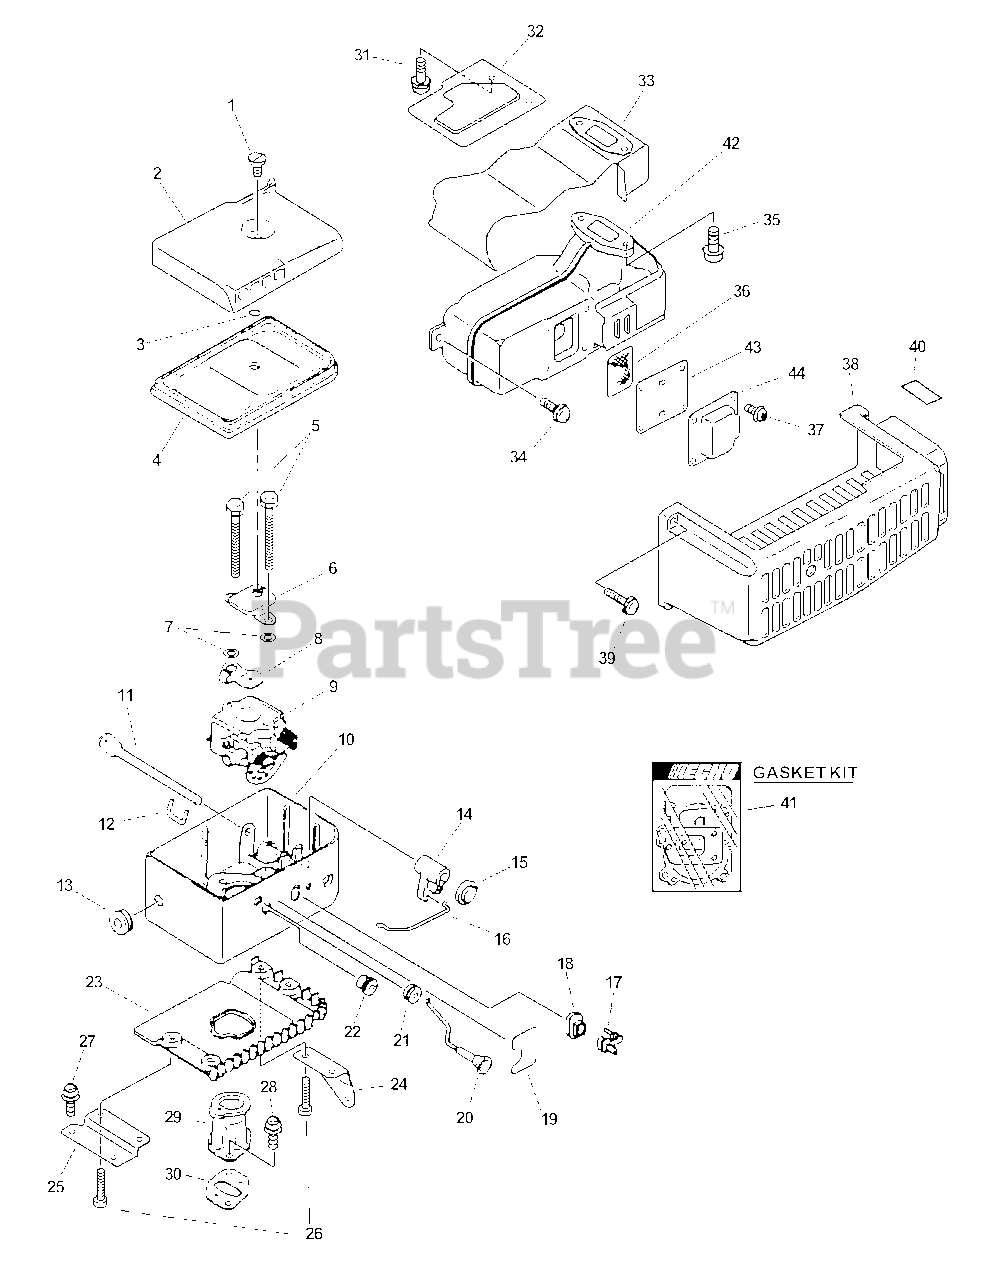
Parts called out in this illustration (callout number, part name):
1	THUMBSCREW
2	COVER, AIR FILTER
3	O-RING - 3
4	FILTER, AIR
5	SCREW - 5X40
6	PLATE, PREVENT
7	WASHER - 5
8	SHUTTER, CHOKE
9	CARBURETOR WT-409B
10	CASE, CARBURETOR
11	SHAFT, THROTTLE
12	CONNECTOR, THROTTLE
14	ARM, THROTTLE LEVER
15	GUIDE, THROTTLE ROD
16	ROD, THROTTLE
19	LABEL
20	ROD, CHOKE
22	GROMMET
23	INSULATOR
26	SCREW - 5X25
27	SCREW - 4X10
28	SCREW - 5X14
29	ADAPTOR, INTAKE
30	GASKET, INTAKE
31	SCREW - 4X10
32	INSULATOR
33	GASKET, EXHAUST
34	SCREW - 5X14
35	SCREW - 5X16
36	SCREEN, SPARK ARRESTOR
37	SCREW - 4X10
38	COVER, EXHAUST
39	SCREW - 5X20
40	LABEL - HOT SURFACE
41	GASKET KIT
42	MUFFLER
43	GASKET, EXHAUST
44	GUIDE, EXHAUST
